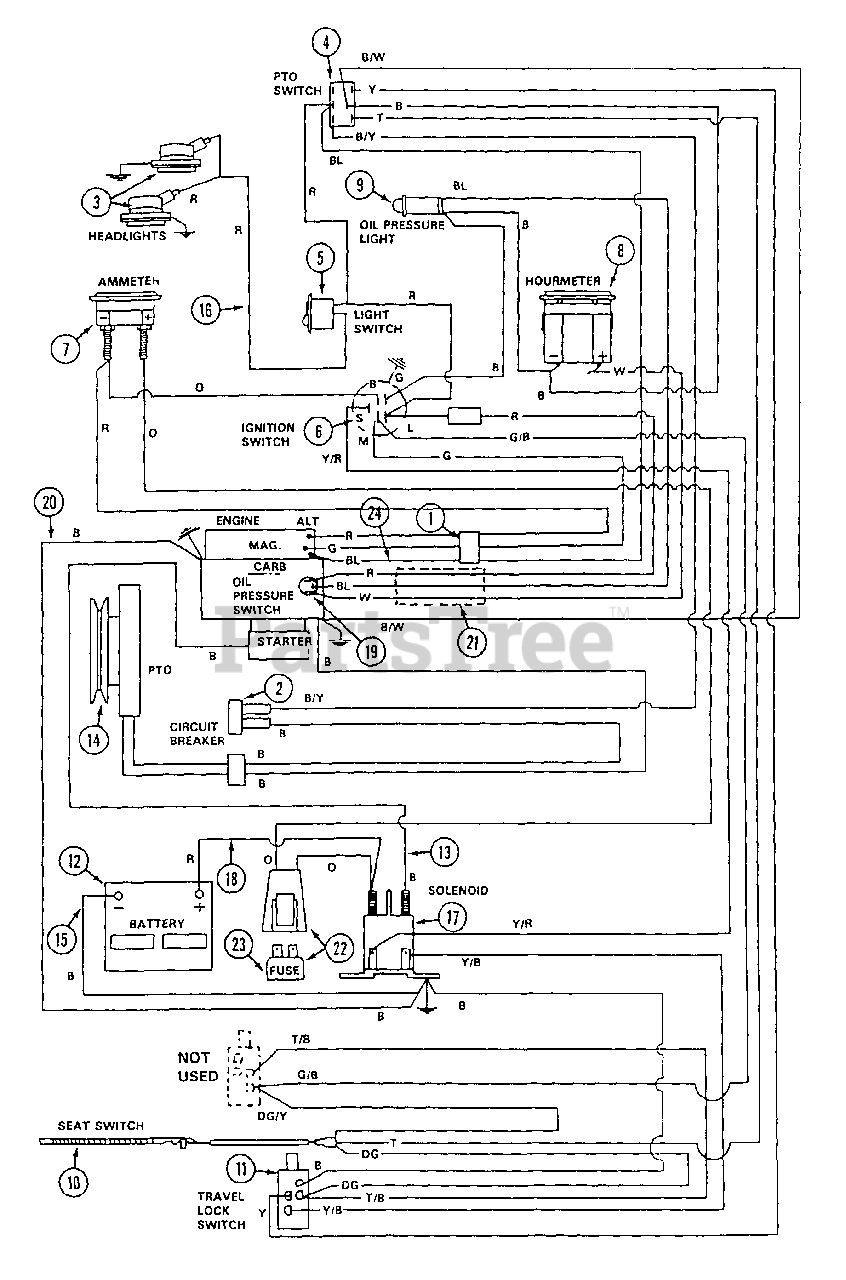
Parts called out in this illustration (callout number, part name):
1	HARNESS - wire, alternator and magneto
2	BREAKER - circuit, 10 amp.
4	SWITCH - PTO
5	SWITCH - headlight
6	SWITCH - ignition
8	METER - hour
10	SWITCH - seat
11	SWITCH - safety
12	BATTERY - 12 volt
13	WIRE - starter
15	CABLE - ground
16	WIRE - headlight
17	SOLENOID - start
18	CABLE - battery positive to solenoid
19	SWITCH - oil light
20	WIRE - ground
21	HARNESS - oil pressure switch
22	KIT - fuse holder
23	FUSE - 30 amp.
24	WIRE - carburetor solenoid
